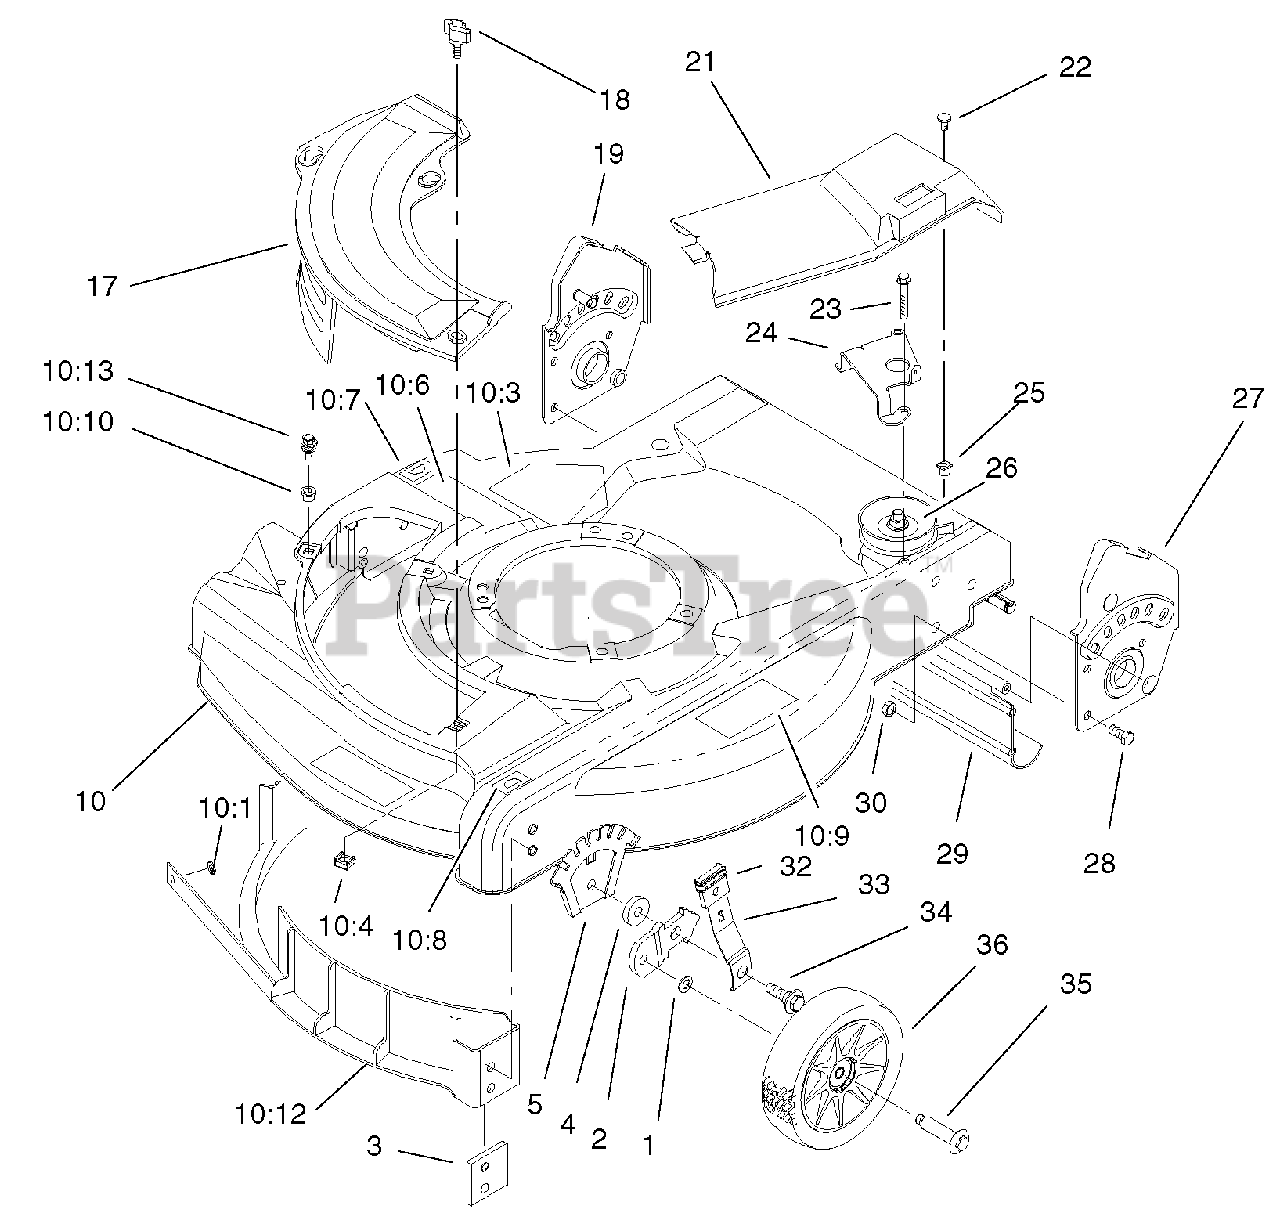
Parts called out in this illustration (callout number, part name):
2	Bracket-Wheel Height Adjustment
3	Plate-Baffle
4	Washer-Wheel
5	Plate-Height Adjustment
10	Deck ASM
10:1	Washer-Flat
10:3	Decal-Danger
10:4	Nut-Cage
10:6	Decal-Warning
10:7	Decal-HOC, RH
10:8	Decal-HOC, LH
10:9	Decal-Warning
10:10	Grommet-Plastic
10:12	Insert-Housing
10:13	Screw-Sems
17	Plate-Mulch
19	Handle Bracket ASM-RH
21	Cover-Drive
23	Screw-HWHTF
24	Guide-Transmission
25	Grommet
26	Gear Case ASM
27	Handle Bracket ASM-LH
28	Screw-HH
29	Shield-Trailing
30	Nut-Lock
32	Knob-Lever, Height Adjustment
33	Arm-Front Spring
34	Bolt-Shoulder
35	Bolt-Shoulder
36	Wheel & Tire ASM
